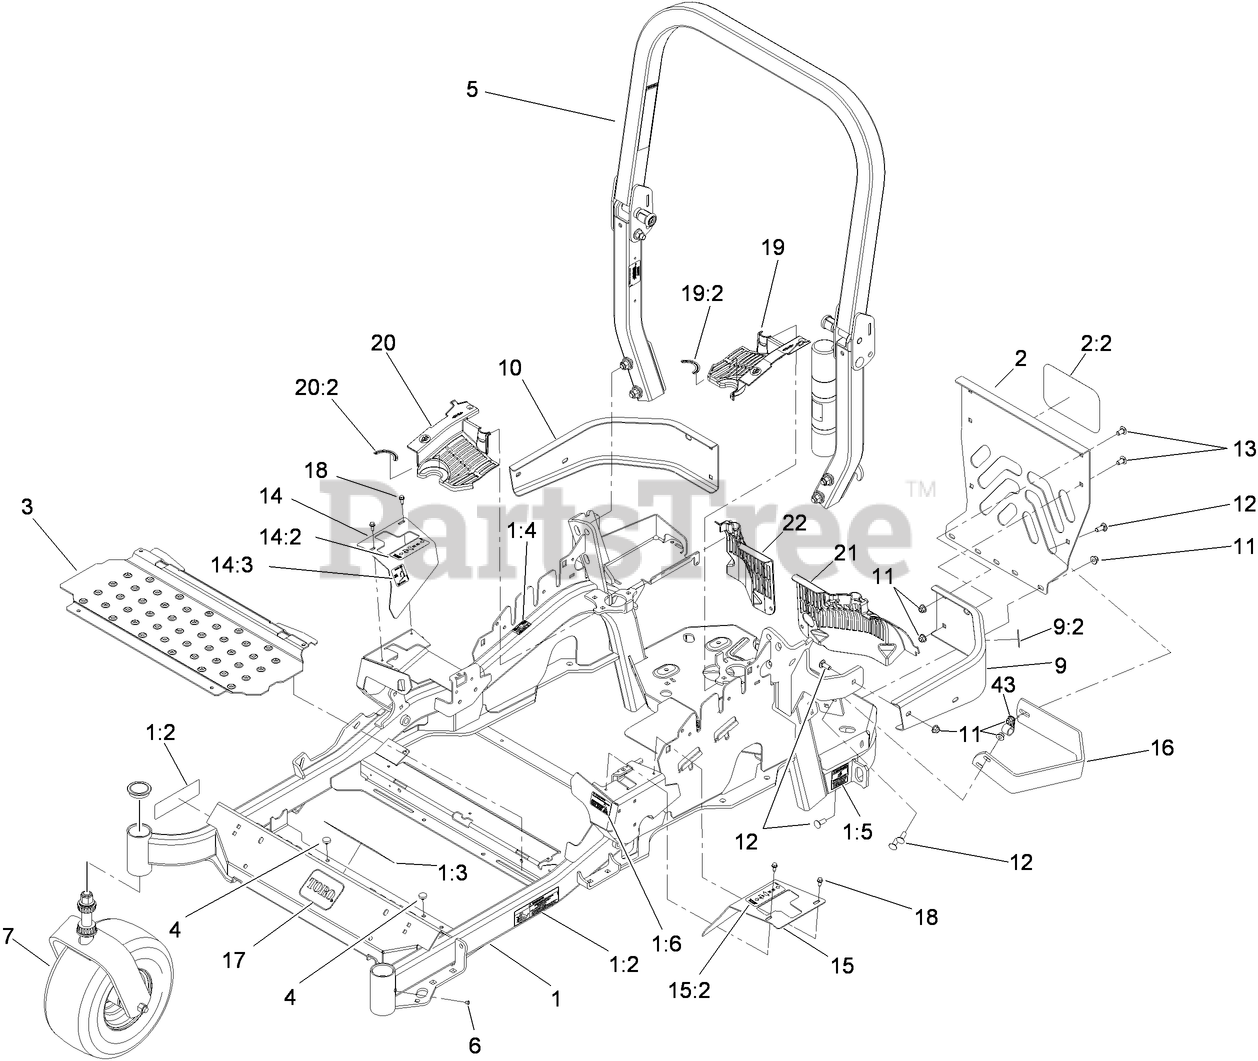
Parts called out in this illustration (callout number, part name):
1	MAIN FRAME ASM
1:2	DECAL-CAUTION
1:3	DECAL-WARNING
1:4	DECAL-BELT DRIVE
1:5	DECAL-ARRESTER, SPARK
1:6	DECAL-FUEL FILL
2	REAR GUARD ASM
2:2	DECAL
3	FLOORPAN
4	BUMPER
5	ROPS ASM
7	Caster Wheel ASM
9	BUMPER-REAR, LH
9:2	DECAL-CAUTION
10	BUMPER-RH
11	NUT-HF, NI
12	SCREW-CARR
13	SCREW-CARR
14	RH MOTION CONTROL COVER ASM
14:2	DECAL-MOTION CONTROL
14:3	DECAL-PARK BRAKE
15	LH MOTION CONTROL COVER ASM
15:2	DECAL-MOTION CONTROL
16	GUARD-MUFFLER
17	DECAL
18	SCREW-HWH
19	LH HYDRO GUARD ASM
19:2	DECAL-HYDRO OIL
20	RH HYDRO GUARD ASM
20:2	DECAL-HYDRO OIL
21	GUARD-HYDRO, REAR (LH)
22	GUARD-HYDRO, REAR (RH)
43	CLIP-LOOM
